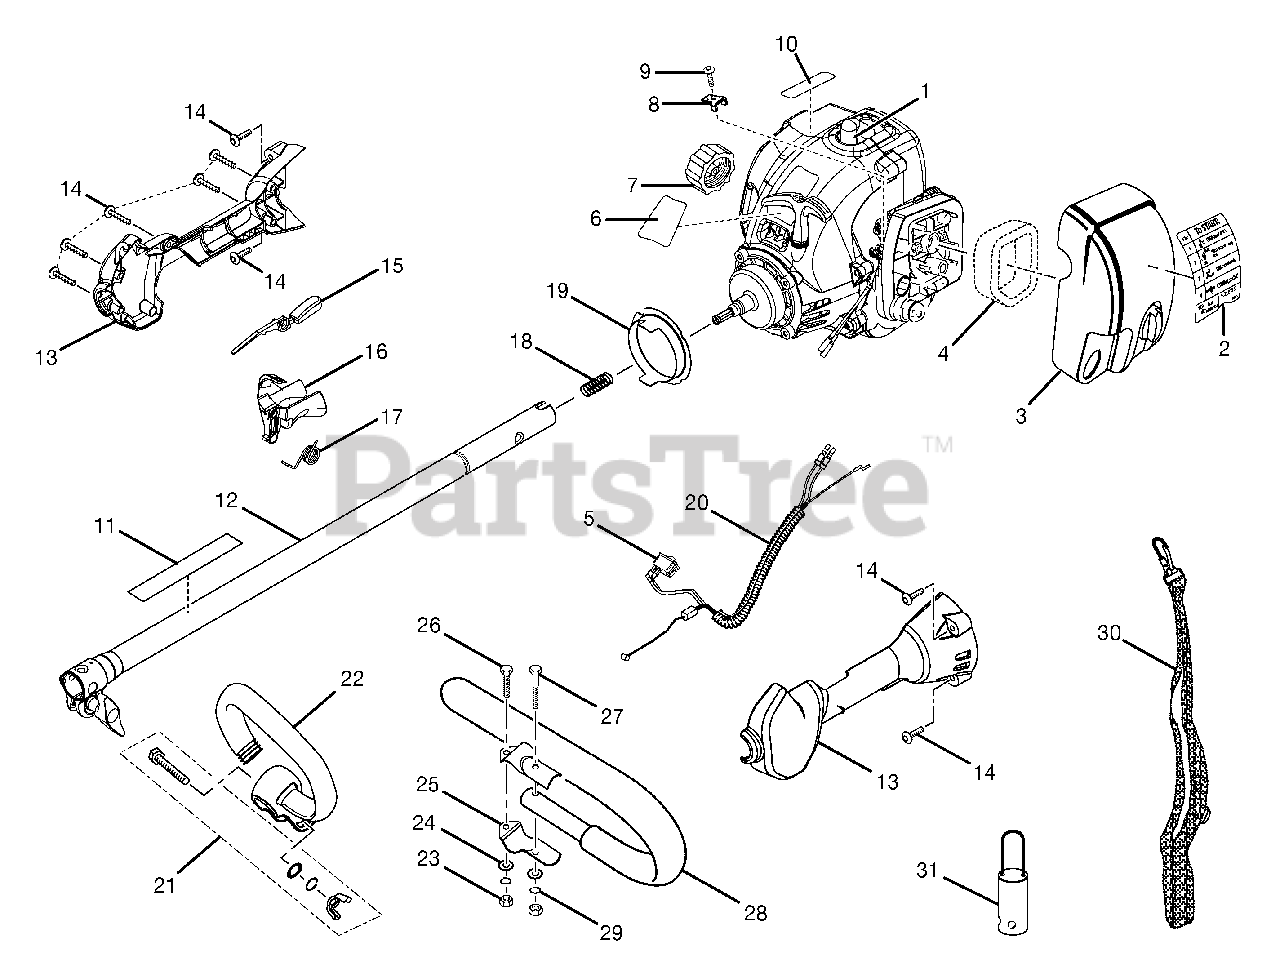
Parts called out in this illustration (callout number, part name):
1	SPARK PLUG
2	STARTING/PRIMER LABEL
3	AIR BOX COVER
4	AIR FILTER
5	SWITCH (MOMENTARY CONTACT)
6	MODEL LABEL (CS30)
8	THROTTLE CABLE CLIP
9	SCREW (M4 X 16 mm TORX PAN HD.)
10	LOGO PLATE
11	WARNING DECAL (CS30 AND SS30)
12	BOOM ASSEMBLY (CS30 AND SS30)
13	HANDLE ASSEMBLY
14	HANDLE SCREW (10-14 X 1 in. TORXT.F.)
15	TRIGGER LOCK
18	COMPRESSION SPRING
19	RING GUARD
20	THROTTLE CABLE ASSEMBLY
21	FASTENER KIT (CS30 AND SS30)
22	"D" HANDLE (CS30 AND SS30)
23	HEX NUT (1/4-20) (BC30)
24	WASHER (BC30)
25	HANDLE BAR CLAMP (BC30)
26	SCREW (1/4-20 X 1 in. HEX CAP)(BC30)
27	BOLT (1/4-20 X 1-1/2 in. HEX HD.) (BC30)
28	"J" HANDLE AND GRIP (BC30)
29	LOCK WASHER (BC30)
30	SHOULDER STRAP (BC30)
31	HANGER CAP
